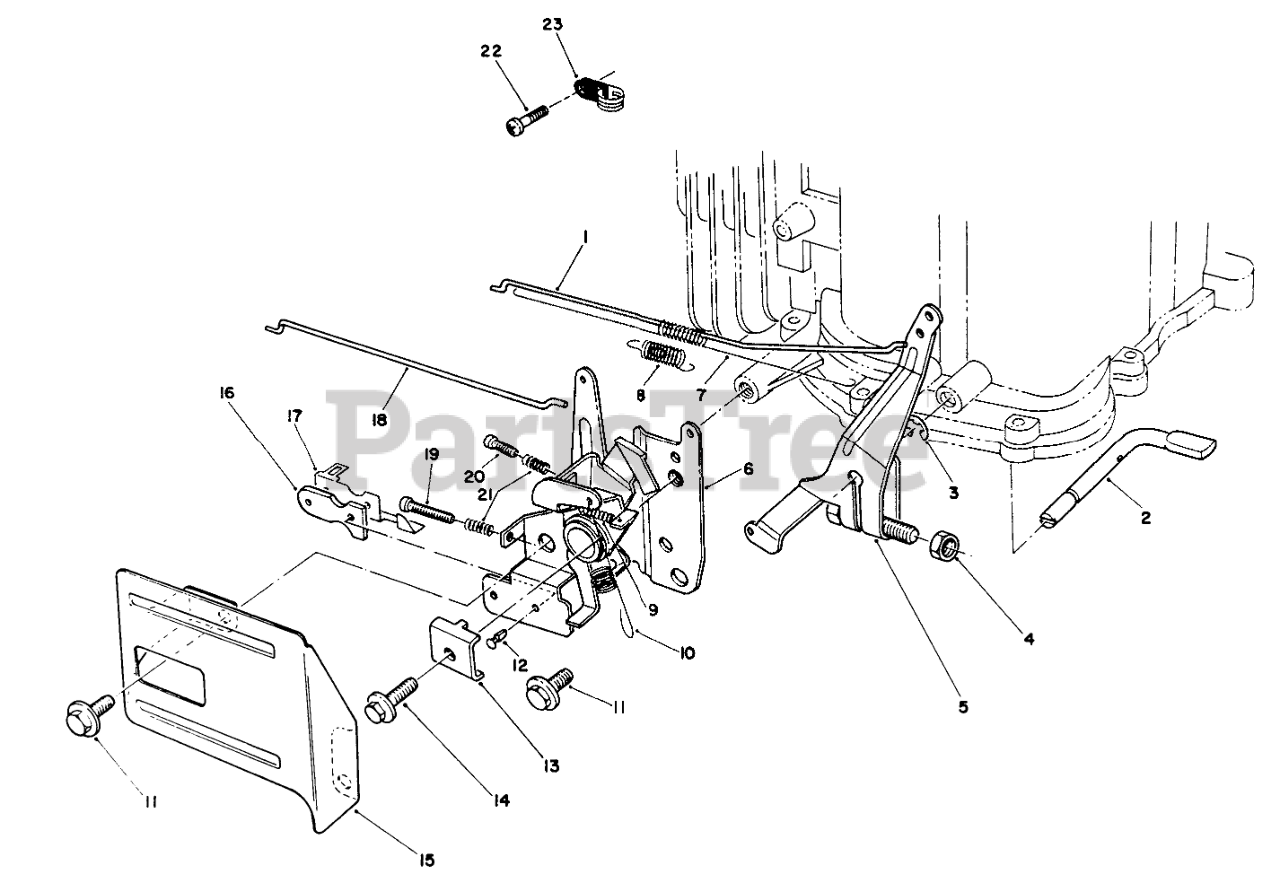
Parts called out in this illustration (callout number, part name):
1	Rod-Carburetor
2	SHAFT
3	E-RING
4	Nut
5	ARM ASM
6	THROTTLE
7	SPRING
8	SPRING
9	SPRING
10	SPRING
12	RIVET
13	CLAMP-CABLE
15	THROTTLE GUARD
16	INSULATOR-KILL SWITCH
17	TERMINAL-KILL SWITCH
18	Rod-Choke
19	SCREW
20	SCREW
21	SPRING
22	SCREW
23	Clamp
